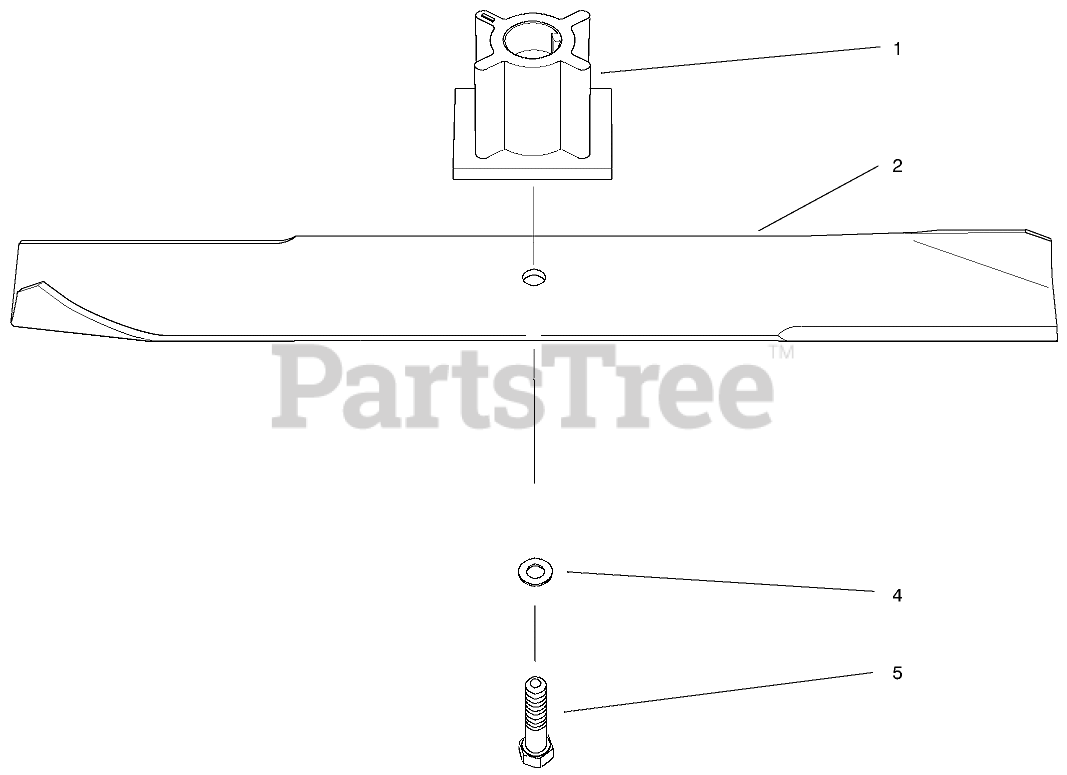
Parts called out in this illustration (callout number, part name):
1	RETAINER-BLADE
2	BLADE-RECYLER
4	WASHER-LOCK
5	BOLT-BLADE
